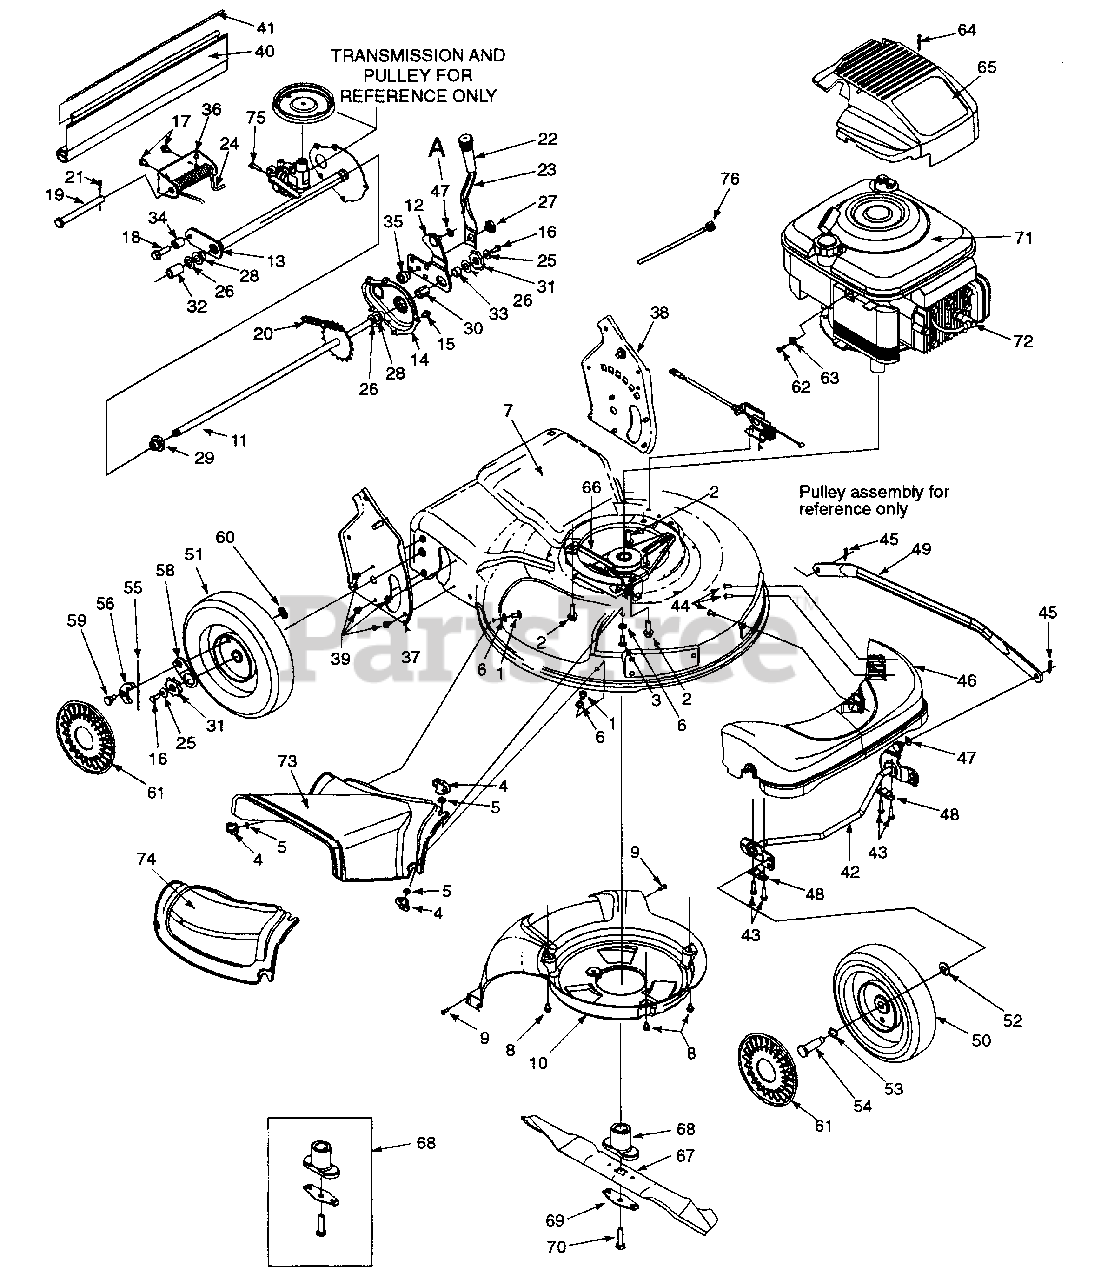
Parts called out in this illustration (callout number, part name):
1	Scr. Carr. 1/4-20 x .62" Lg.
2	Scr. TT:3/8-18:1.00
3	Scr. 1/4-20 x .750
4	Wing Nut 1/4-20
5	Nut, Push .25 I.D. x .50 O.D.
6	Wash. Fl. .334 I.D.x .62 x.03
8	Scr. TT. 1/4-20 x .375
9	Scr. HL. 1/2-14 x .750
10	Baffle
11	Rear Axle Ass'y
16	Cap Screw HH 1/4-20 x .620
17	Scr. AB 1/4-14 x .825
18	Scr. 3/8 116 x .25
19	Clevis Pin .50 Dia. x 4.82 Lg.
20	Chain-Endls. #48 .500P x 24L
21	Cotter Pin .125O.D. x .75
23	Spring Lever
24	Torsion Spring
25	Bell Wash. .285 x .75 x .082
26	Fl. Wash. .508 I.D. 1.000 x .020
27	Nut Shld. .825 Dia. x .165 Lg.
28	Hx. Flg. Brg. .506 I.D. x .590 L.
29	Hx. Flg. Brg. .506 I.D. x.715 L.
30	Hx. Slv. Brg. .504 I.D. x .830 L.
31	Wheel Rachet
32	Spa. .550 I.D. x .750 O.D.
33	Spa. .51 .D. x .70 O.D. x 38 L.
34	Spa. .385 x .624 x .700
35	Shld. Spa. .385 I.D. x .715 Lg.
40	Trail Shield
41	Trail Shield Wire
43	Hx Scr. Wash Hd. Hi.-Lo.
44	Scr. Torx, Truss Hi.-Lo.
45	Cotter Pin .072 x 1.12 Lg.
46	Fr. Axle Cover
47	Bowed Washer
48	Bush. Block .505 Dia. x .62
50	Wheel 8 x 2
51	Wheel 9 x 2
52	Spr. Wash. .401 x .870 x .063
53	Wave Wash .510 x .750 x .017
54	Shldr Scr .498 x 1.445 x 3/8-16
55	Spring, Ratchet, Plastic
56	Pawl - R.H.
58	Ratchet Pawl Plate
59	Scr. Shld. .340 x .285
60	Top Lock Tab Weld Nut 1/4-20
61	Hubcap - Yellow
62	Screw .620 Hx. Slt. Wsh.
63	Casing Clamp, Throttle
64	Shroud Screw
65	Engine Shroud
66	Belt
67	21" Mulching Blade
68	Blade Adapter Kit
69	Blade Bell Suport
70	Hex Bolt 3/8-24 x 2.5" Lg.
72	Spark Plug Insulator
73	Side Discharge Chute
74	Mulch Cover
75	Hex Scr. 5/16-18
76	Cable Tie
